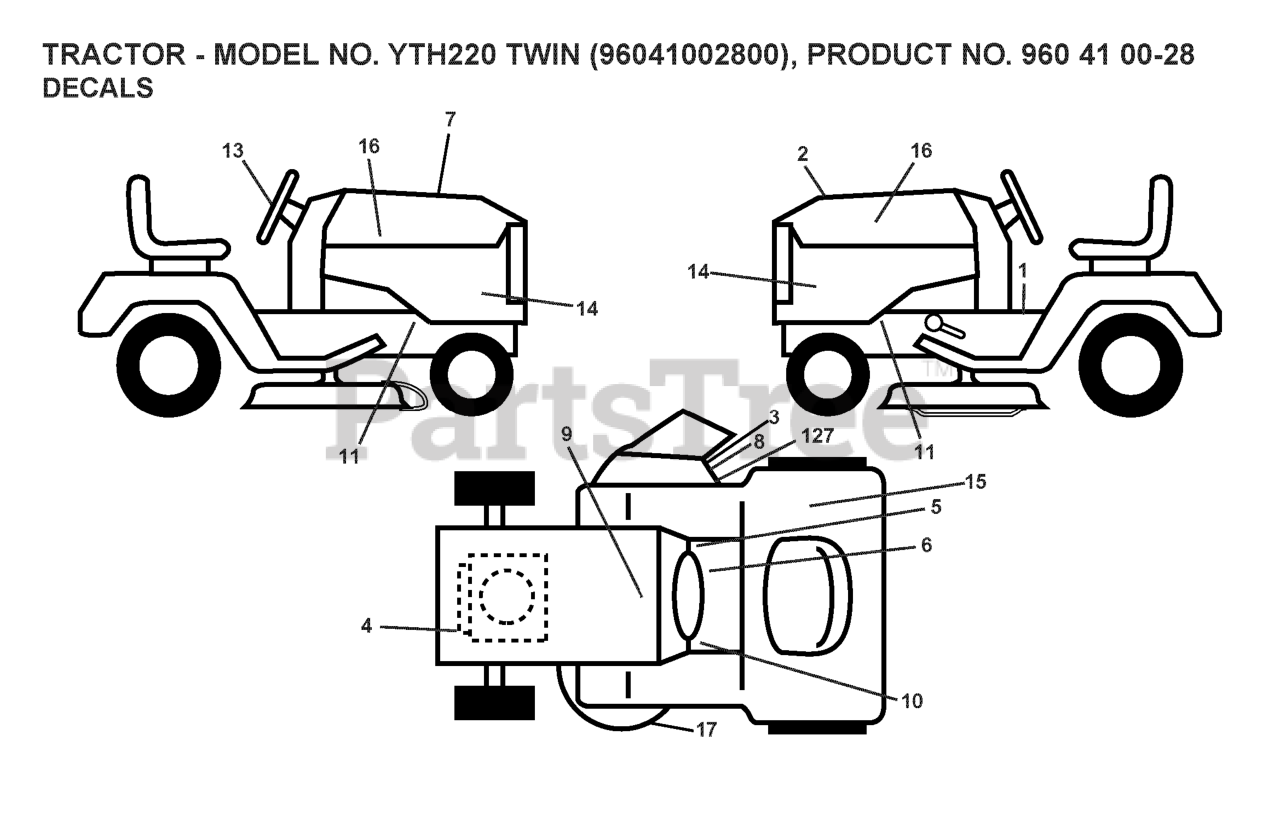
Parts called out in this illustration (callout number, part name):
1	LABEL
2	DECAL.HOOD.TOP.INSERT.
4	DECAL
5	DECAL PARK BRAKE
6	DECAL
7	DECAL RPL KO
8	DECAL.INTERNATIONL.CUTFINGER
9	DECAL BTRY SYMBOLS
10	DECAL
13	DECAL.WHEEL.STRG.LGN.H
14	DECAL PNL SD.
15	DECAL.FENDER
16	DECAL.HOOD.NAMELOGO.HUSQ
17	DECAL.MOWER.SCH.48/54
18	DECAL, DEFLECT WARNING
